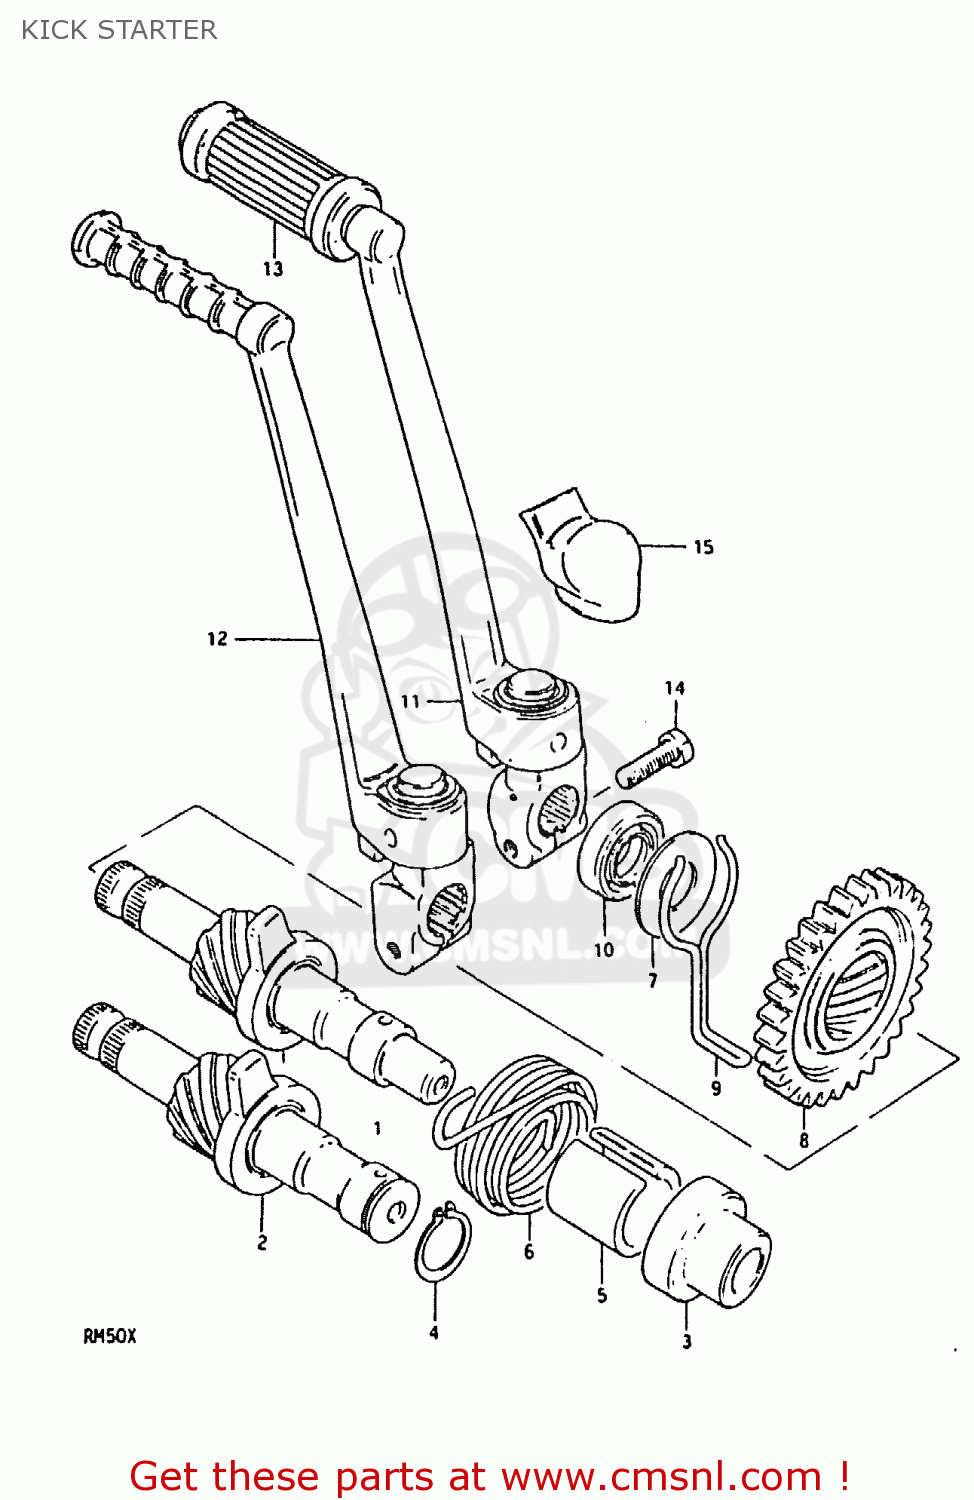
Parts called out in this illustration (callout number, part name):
1	SHAFT,KICK STARTER
2	SHAFT,KICK STARTER
3	HOLDER,KICK STARTER SHAFT
4	CIRCLIP,16MM
5	GUIDE,KICK STARTER SFT SPRING
6	SPRING
7	WASHER
8	GEAR,KICK STARTER DRIVE(NT:30)
9	RETAINER,SNAP
10	SEAL,OIL(14X24X6)
11	LEVER ASSEMBLY,KICK STARTER
12	LEVER ASSY,KICK STARTER
13	RUBBER,KICK STARTER PEDAL
14	BOLT
15	COVER,KICK STARTER PEDAL
